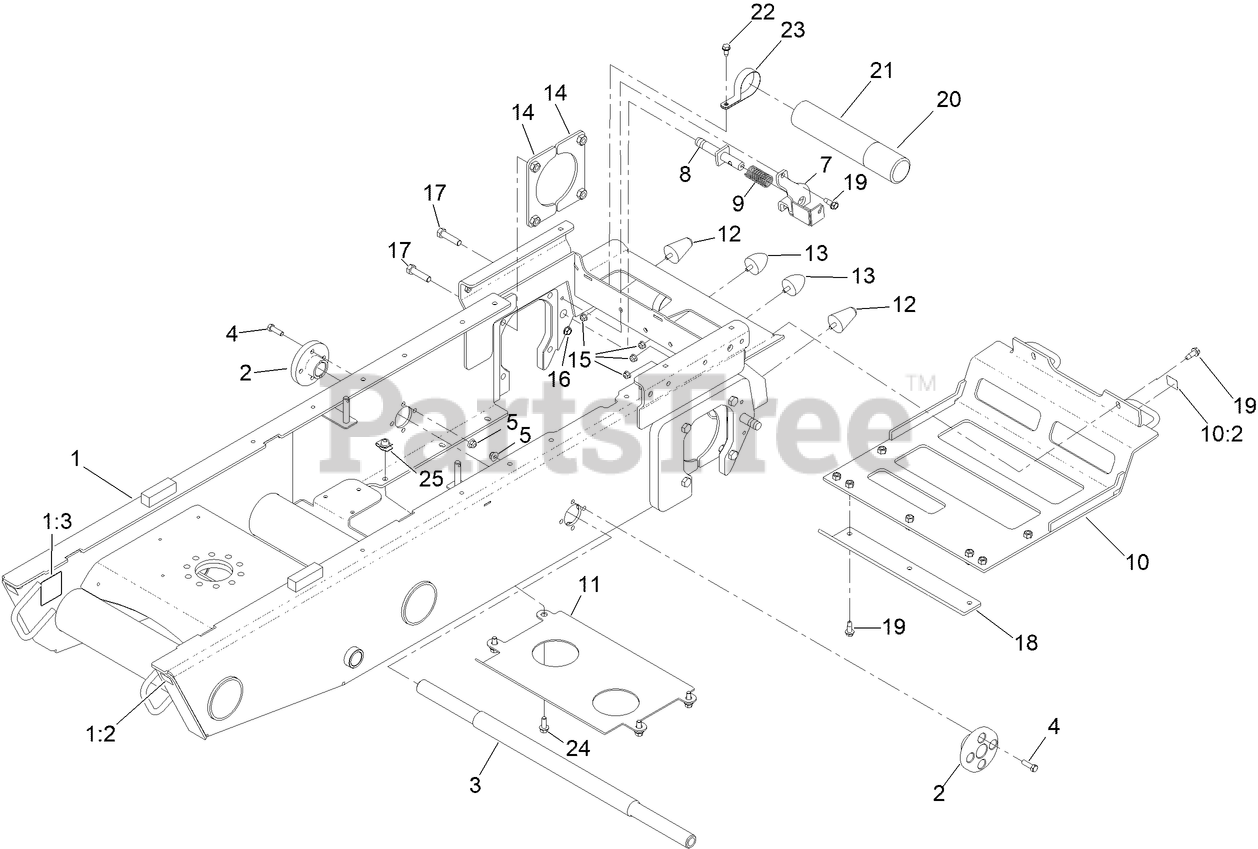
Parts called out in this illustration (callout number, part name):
1	FRAME ASM- SWIVEL
1:2	DECAL-TIEDOWN
1:3	DECAL-LIFT HERE
2	HUB-MOUNT, TRACK
3	SHAFT-TRACK
4	SCREW-HH
5	NUT-HF, NI
7	BRACKET-BRAKE
8	SHAFT-BRAKE
9	SPRING-COMPRESSION
10	PLATE-SIDE
10:2	DECAL-TIEDOWN
11	SKID PLATE, HYDRAULIC TANK
12	BUMPER-RUBBER
13	BUMPER-RUBBER
14	HYDRO MOUNTING PLATE ASM
15	NUT-HF, NI
16	SCREW-TAPPING
17	SCREW-HH
18	PLATE-SKID
19	SCREW-TAPPING
20	CAP-HOUSING
21	TUBE-MANUAL
22	SCREW-HWHTF
23	CLAMP-R
24	SCREW-HHF
25	NUT-TINNERMAN
